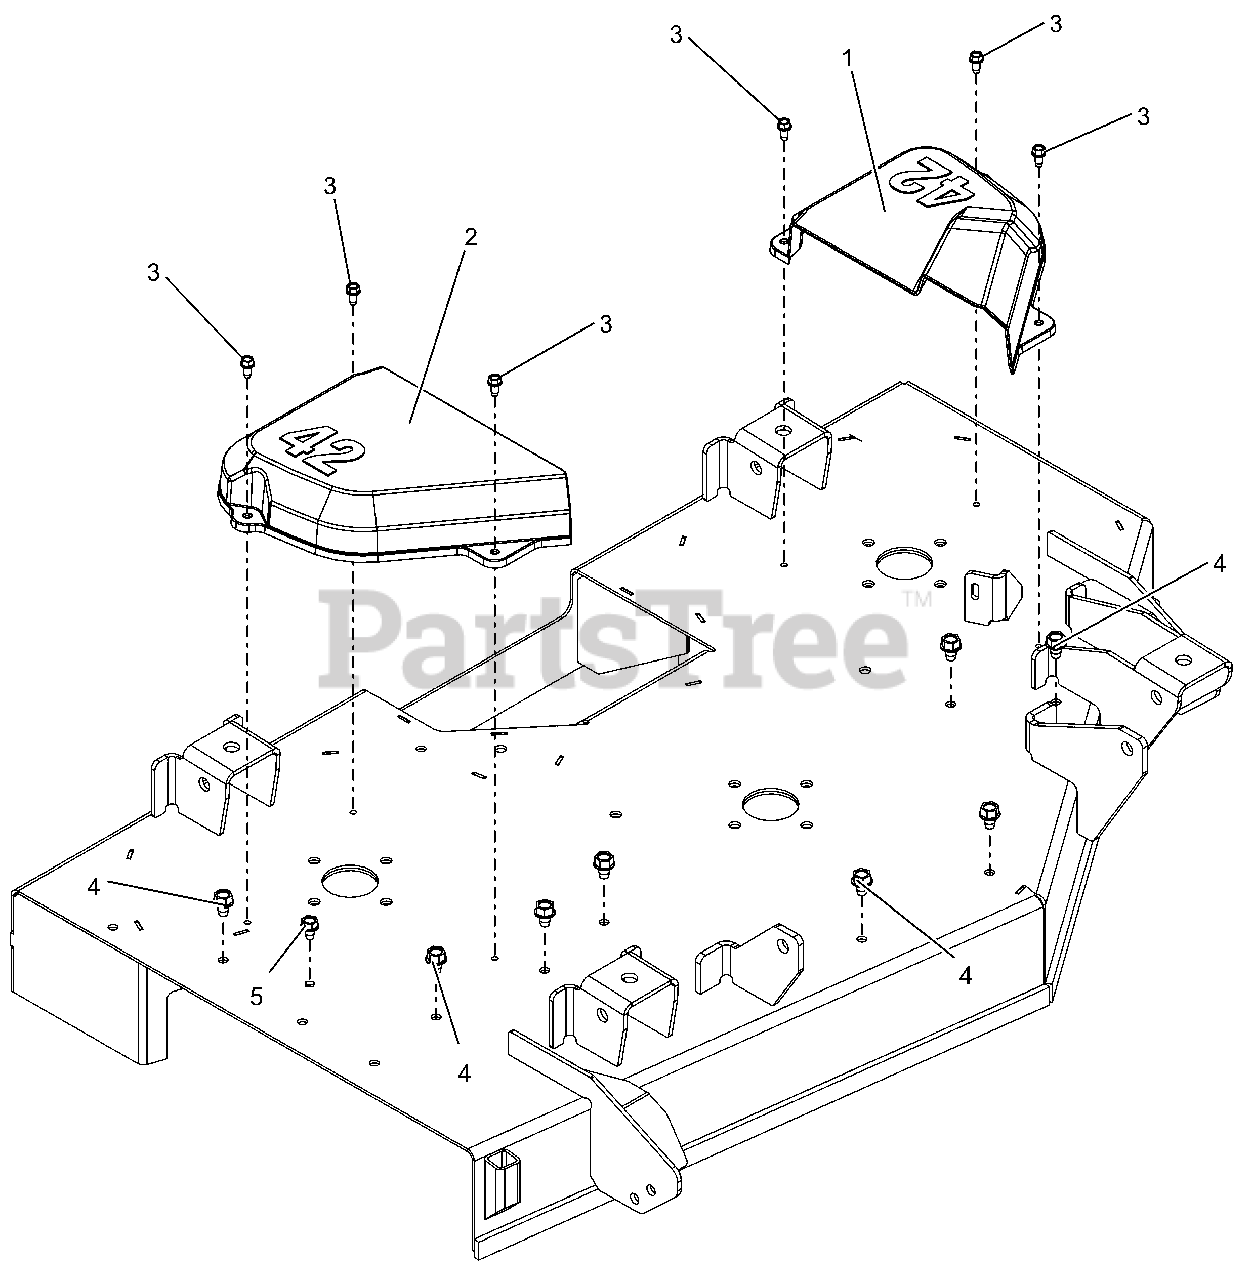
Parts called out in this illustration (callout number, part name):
1	COVER, BELT 42" LH
2	COVER, BELT 42" RH
3	SCR-TAP .25-20X.50 HWH ZCC
4	SCR,TAP .375-16X.50 HWH TR ZCC
5	SCR,TAP .312-18X.50 HWH TR ZCC
